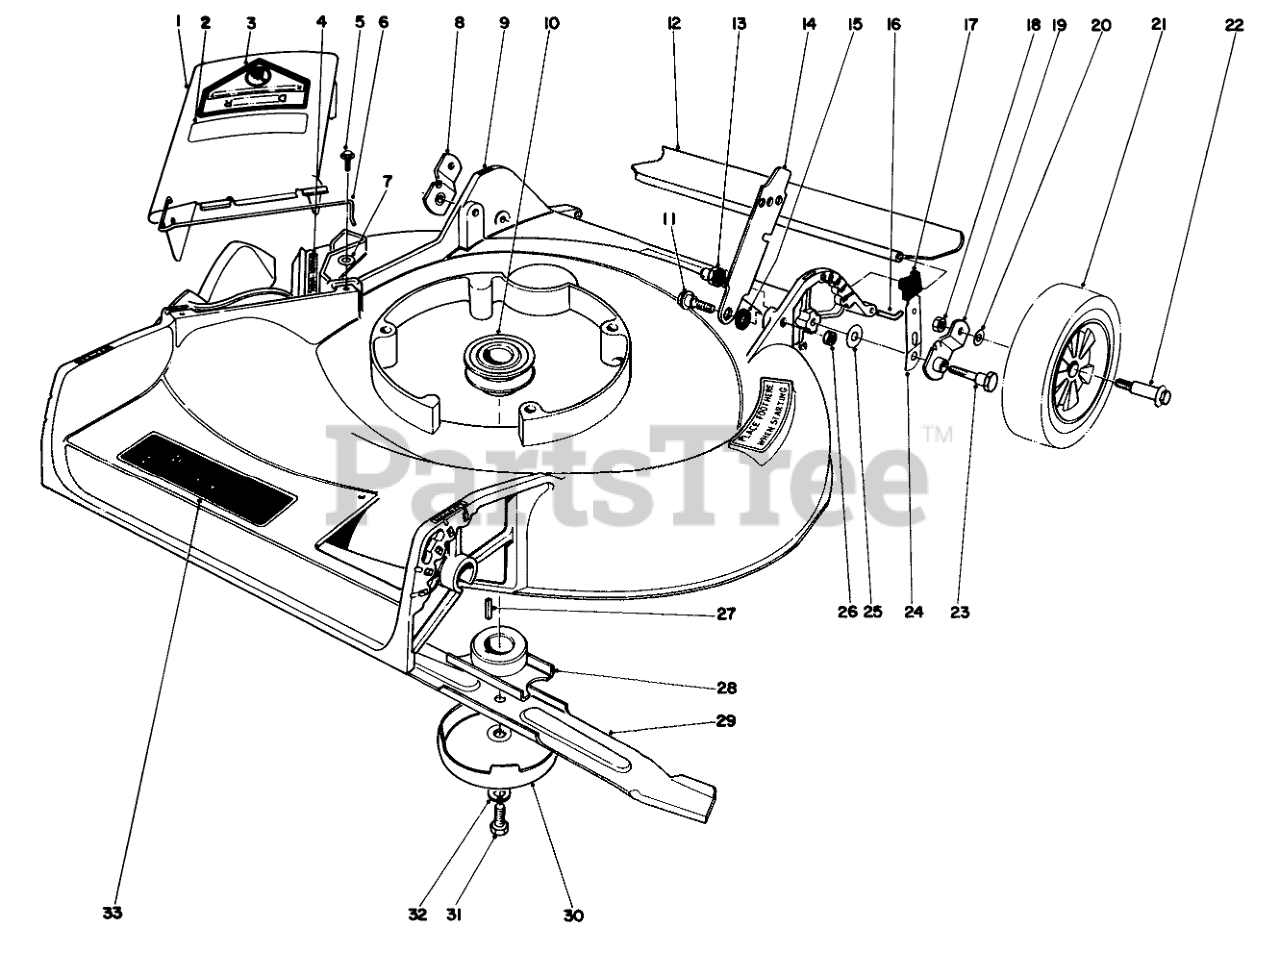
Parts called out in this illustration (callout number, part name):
1	Deflector Cover Assembly (Incl. Ref. #2, 3 & 6)
2	DECAL DEFLECTOR
3	DECAL-DANGER
4	Decal
5	SCREW
6	SPRING HINGE
7	WASHER-FLAT
8	Pivot Arm
9	Housing
10	DRIVER PULLEY
11	SCREW-SHOULDER
12	REAR SAFETY SHIELD 21
13	HANDLE PIVOT NUT
14	Latch
15	HANDLE LATCH SPACER
16	SHIELD ROD
17	KNOB-ARM
18	Nut
19	Pivot Arm
20	WASHER
21	WHEEL TIRE ASM 8 IN
22	BOLT-WHEEL
23	5/16-18 PIVOT SCREW
24	SPRING ARM ASM
25	WASHER-PIVOT
26	Nut
27	KEY-SQUARE
28	Blade Retailer
29	Blade
30	AntiScalp Cup
31	SPECIAL SCREW
32	WASHER-LOCK
33	Decal-Side Discharge
